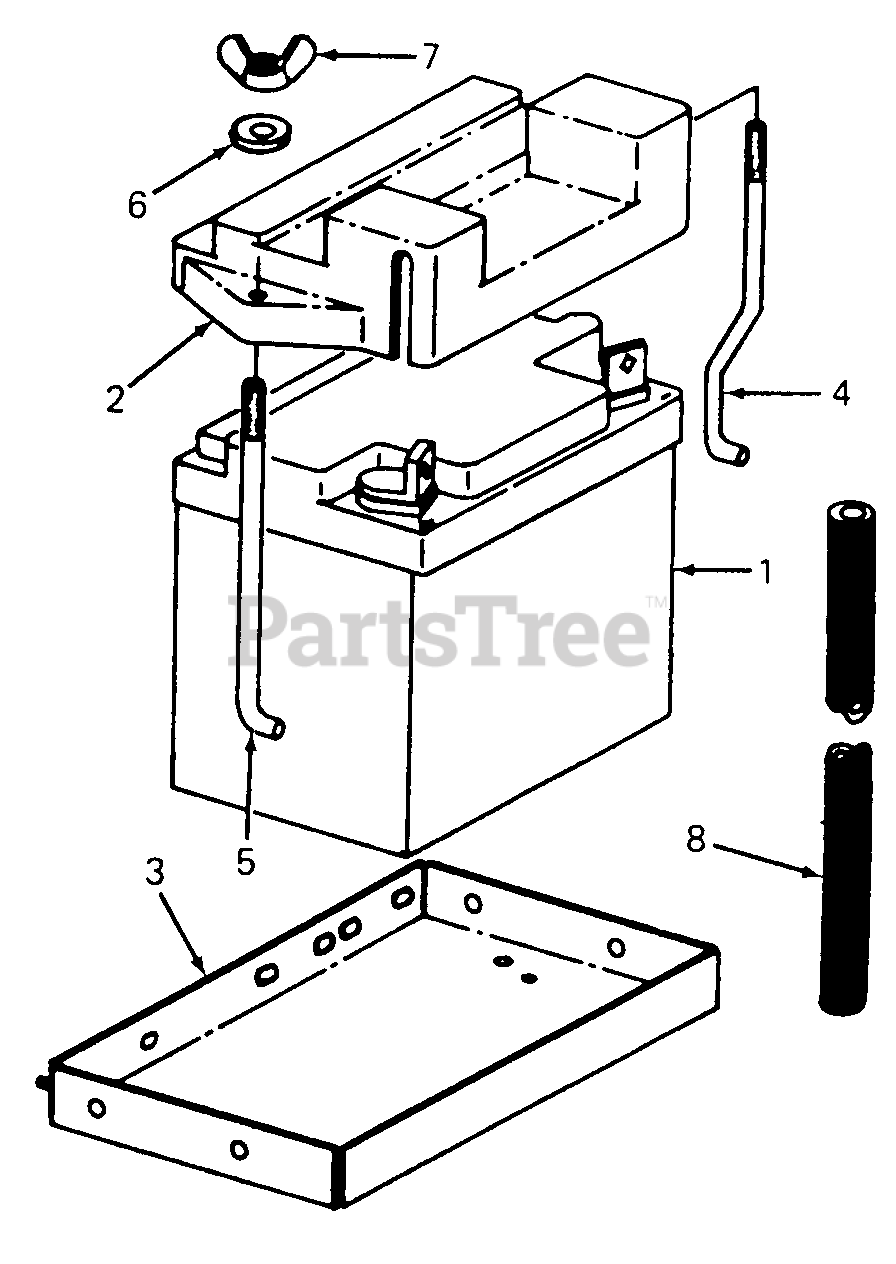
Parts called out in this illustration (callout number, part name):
1	Battery, 12 Volt
2	Cover W/Graphic, Battery
3	Tray, Battery
4	Rod, Battery Cover LH
5	Rod, Battery Cover RH
6	Washer, .281 X .500 X .056
7	Nut, 1/4 Wing
8	Hose, Battery Drain 48 in. Long
